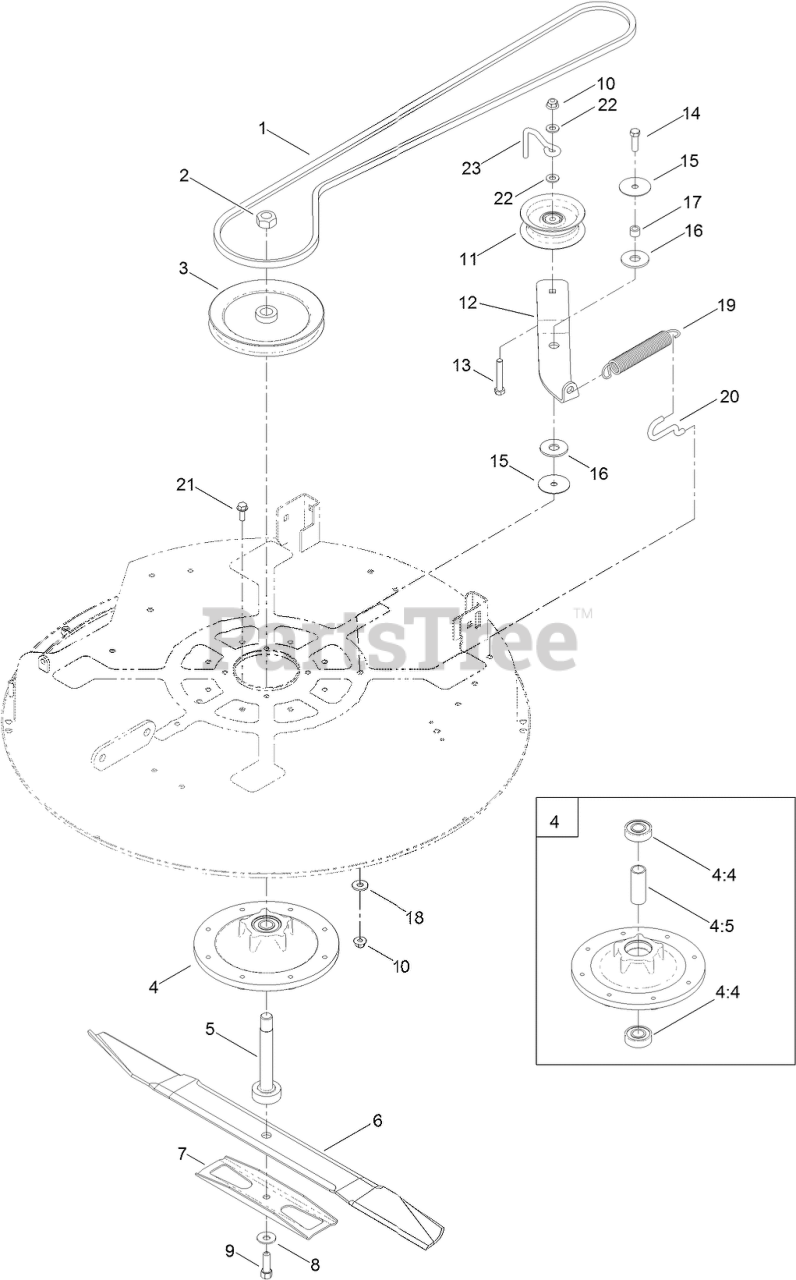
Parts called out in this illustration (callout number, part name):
1	V-BELT, 81.8 INCH
2	NUT-HEX
3	PULLEY-DECK
4	SPINDLE HOUSING ASM
4:4	BEARING-BALL
4:5	SPACER-BEARING
5	SHAFT-SPINDLE
6	BLADE-RECYCLER, 31.35 INCH
7	STIFFENER
8	WASHER-BELLEVILLE
9	SCREW-HH
10	NUT-HF, NI
11	PULLEY-IDLER, FLAT
12	ARM-IDLER
13	SCREW-HH
14	SCREW-HH
15	WASHER
16	WASHER-FRICTION, COMPOSITE
17	SPACER
18	WASHER-HARDENED
19	SPRING-EXTENSION
20	HOOK-RETURN, SPRING
21	SCREW-TAPTITE
22	WASHER-FLAT
23	GUIDE-IDLER, BELT
